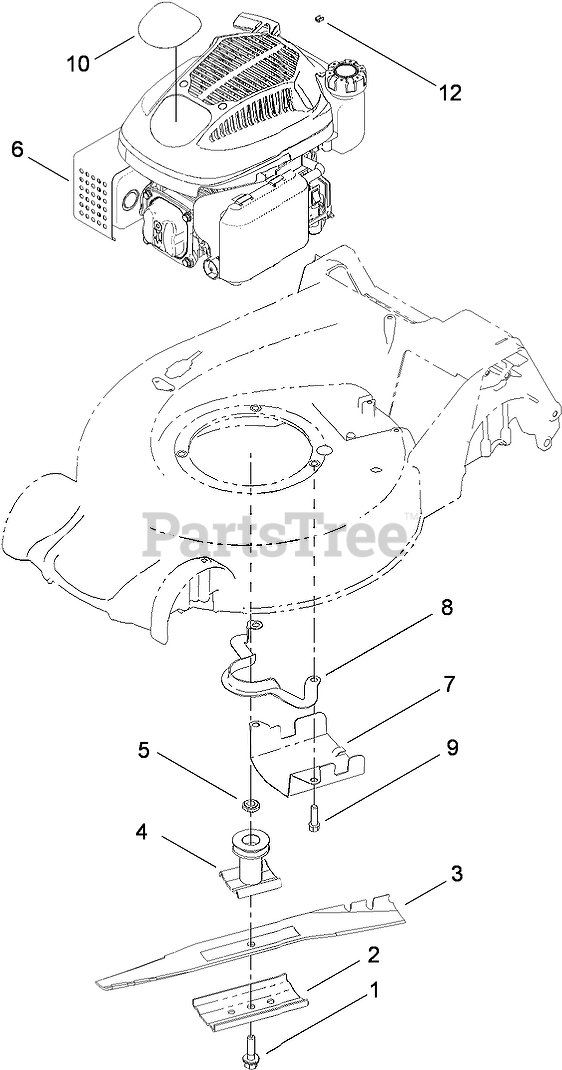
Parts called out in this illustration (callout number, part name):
1	BOLT-BLADE
2	SUPPORT-BLADE
4	DRIVER-BLADE
5	Spacer-Driver
6	ENGINE-LC1P65FA
7	SHIELD-GRASS
8	GUIDE-BELT
9	SCREW-MOUNT, ENGINE
10	DECAL-ENGINE
12	STOP-ROPE
